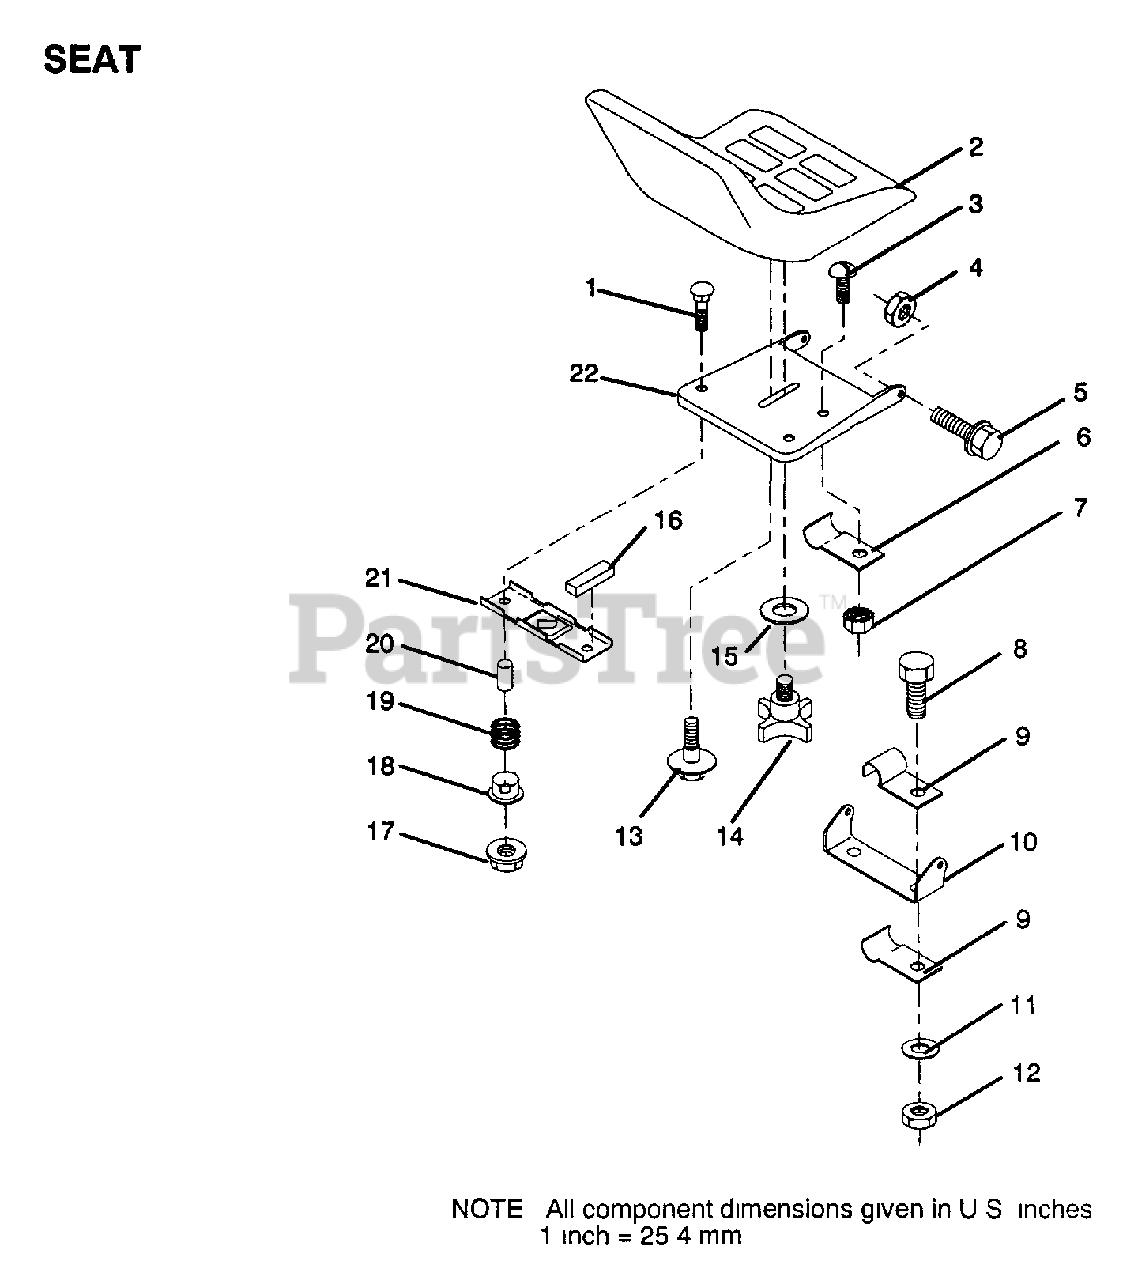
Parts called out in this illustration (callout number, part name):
1	BOLT
7	"NUT,KEPS"
9	"CLIP,INSULATOR"
11	WASHER
13	"BOLT,SHOULDER"
14	"KNOB 1/2"" YT"
15	WASHER
16	STRIP FORM
18	BUSHING
19	SPRING
20	SPACER SPLIT
21	BRKT SWITCH
